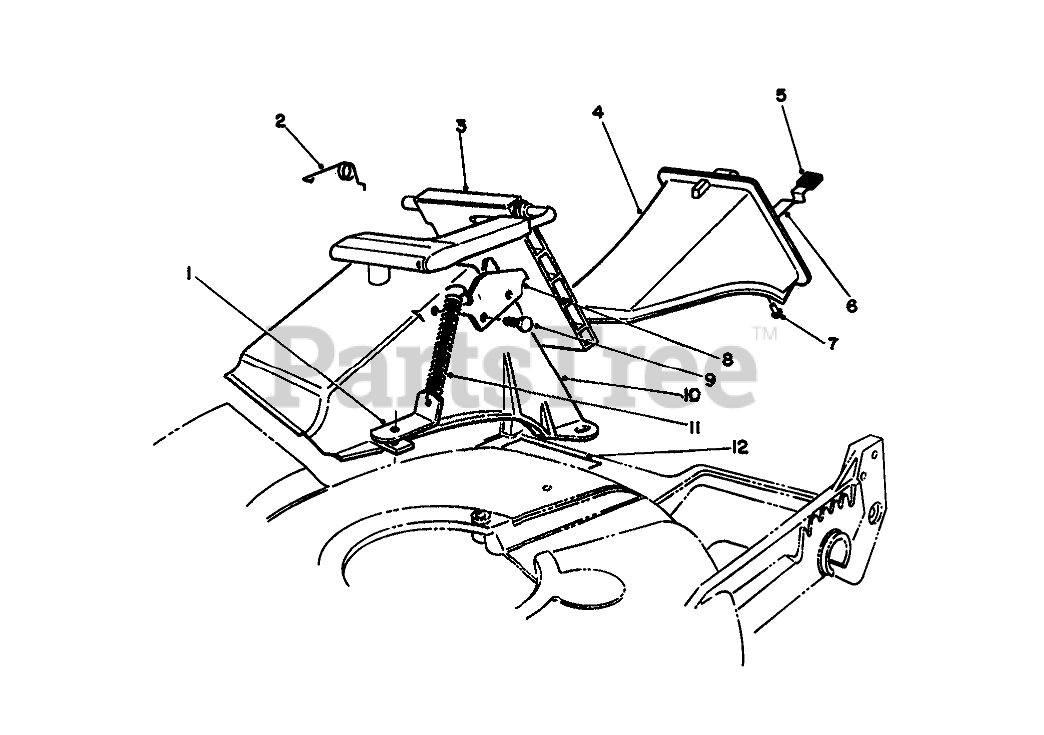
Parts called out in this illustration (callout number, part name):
1	Bracket-Spring
2	RETAINER-DOOR
3	DOOR ASSEMBLY
4	Plug-Assembly (Incl. Ref. #11-13)
5	Grip-Latch
6	LATCH-PLUG, DISCHARGE
7	RIVET-HEAD, FLAT
8	DOOR LATCH PLATE
9	SCREW-PLASTITE
10	DISCHARGE TUNNEL
11	SPRING-DOOR
12	DECAL - CAUTION
